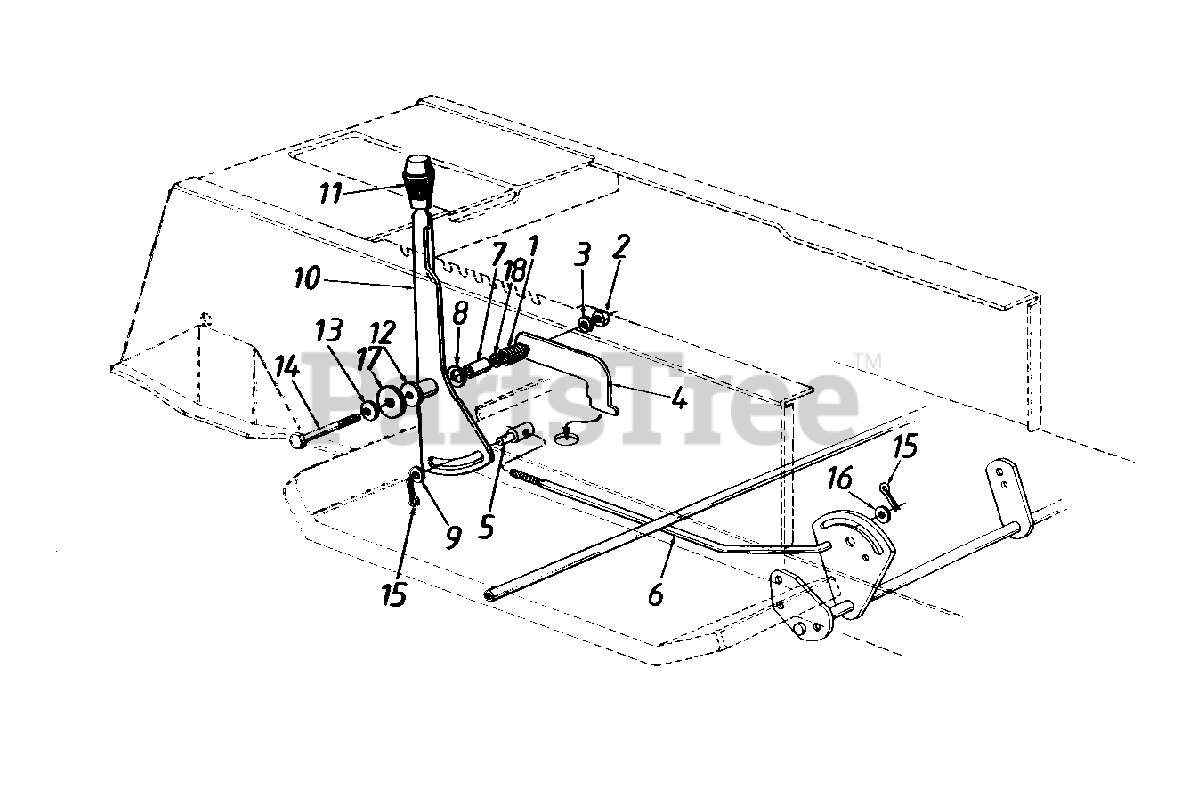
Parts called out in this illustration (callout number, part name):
1	Compression Spring
2	Hex Nut 5/16-18 Thd.
3	L-Wash. 5/16" I.D.
4	Shift Lever Support
5	Ferrule 3/8-24 Thd.
6	Speed Control Rod
7	Spacer 1.56" Lg.
8	Bell-Wash. .505" I.D. x 1"
9	Fl-Wash. .385" I.D. x .87"
10	Speed Selector Lever
11	Shift Knob
12	Spacer 1.46" Lg.
13	Fl-Wash. .345" I.D. x .88"
14	Hex Bolt 5/16-18 x 3.25" Lg.
15	Cotter Pin 3/32" Dia. x 1"
16	Fl-Wash. .469" I.D. x .88"
17	Fl-Wash. .34" I.D. x 2.25"
18	Speed Nut 5/16-18 Thd.
